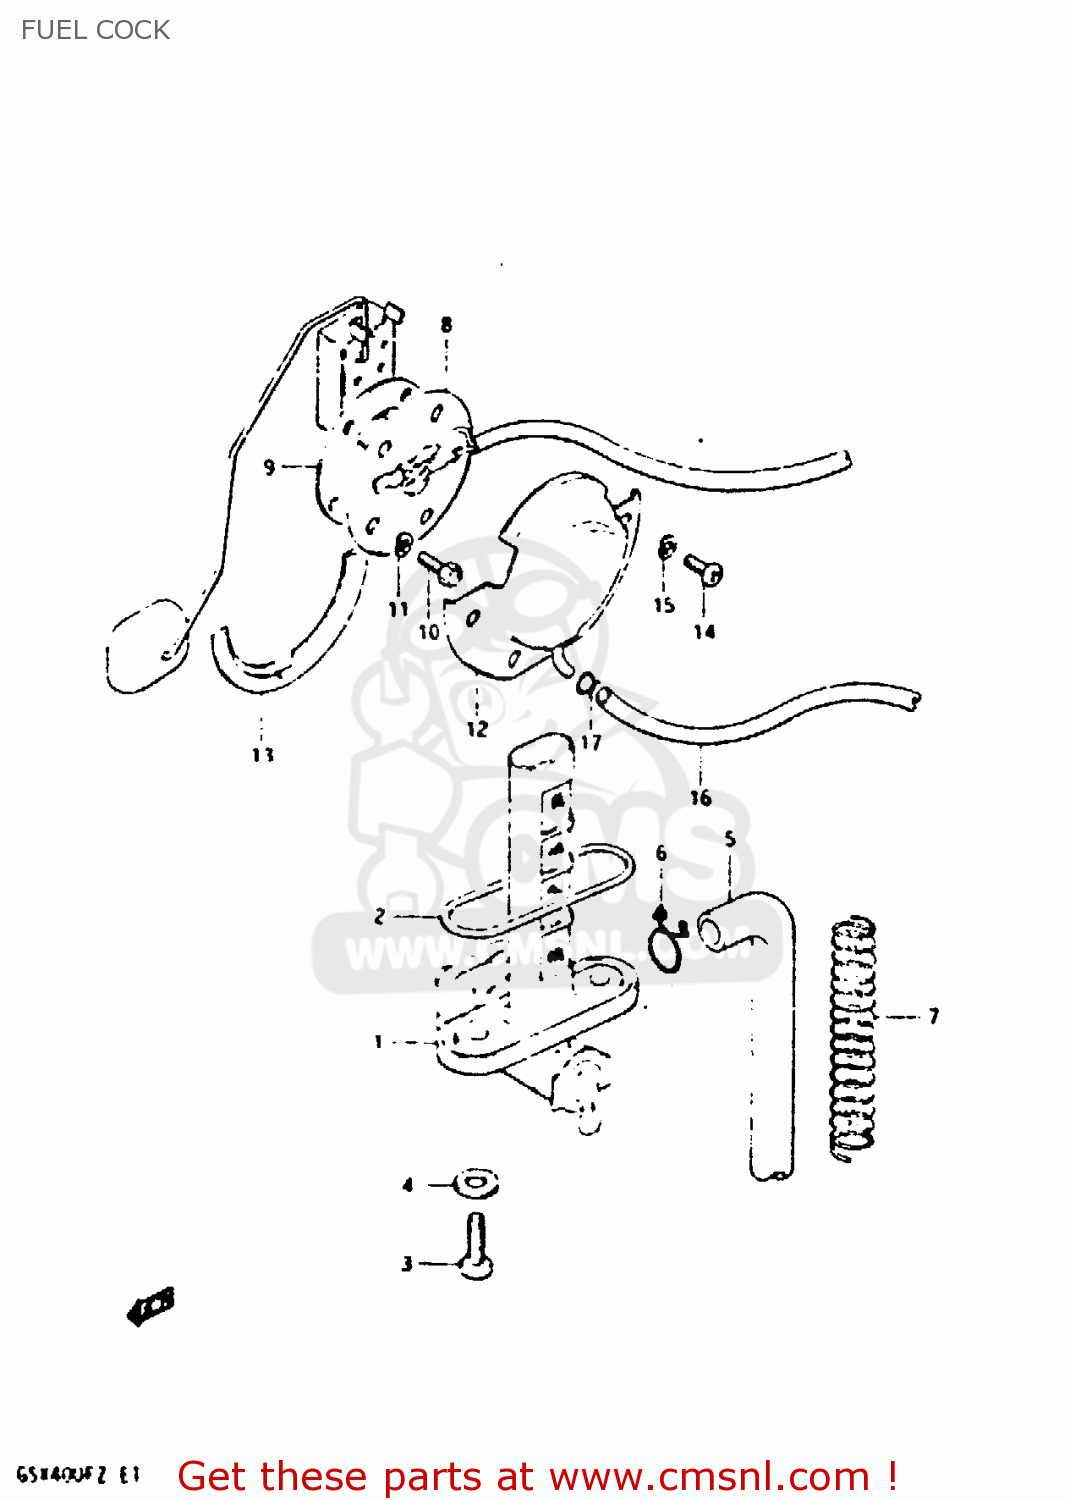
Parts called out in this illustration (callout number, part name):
1	COCK ASSEMBLY,FUEL
2	O RING
3	BOLT(6X20)
4	GASKET
5	HOSE
6	CLIP
7	SPRING
8	GAUGE, FUEL LEVER
9	GASKET,FUEL LEVEL GAUGE (NAS)
10	BOLT
11	LOCK WASHER
12	PLATE,FUEL DRAIN
13	GASKET (NAS)
14	SCREW
15	LOCK WASHER
16	HOSE,FUEL
17	CLIP
